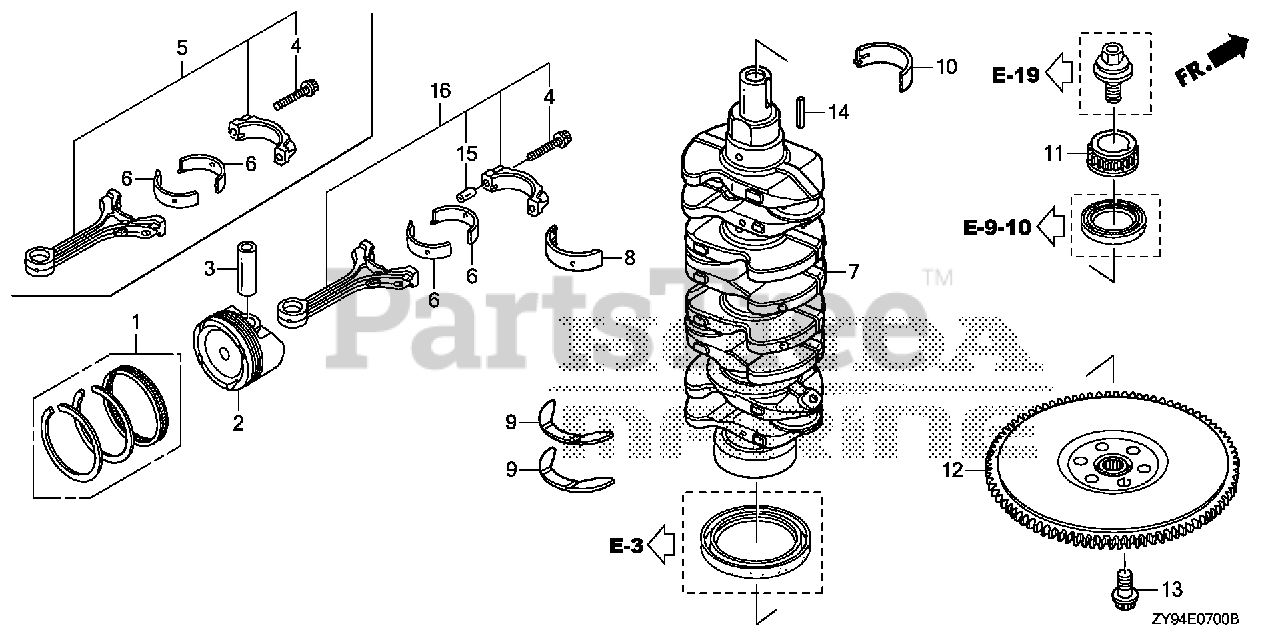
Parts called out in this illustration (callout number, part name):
1	RING SET, PISTON (STD)
1	RING SET, PISTON (0.25)
2	PISTON (STD)
2	PISTON (0.25)
3	PIN, PISTON
4	BOLT, CONNECTING ROD
5	ROD, CONNECTING
6	BEARING A, CONNECTING ROD (BLUE) (DAIDO)
6	BEARING B, CONNECTING ROD (BLACK) (DAIDO)
6	BEARING C, CONNECTING ROD (BROWN) (DAIDO)
6	BEARING D, CONNECTING ROD (GREEN) (DAIDO)
6	BEARING E, CONNECTING ROD (YELLOW) (DAIDO)
6	BEARING F, CONNECTING ROD (PINK) (DAIDO)
6	BEARING G, CONNECTING ROD (RED) (DAIDO)
7	CRANKSHAFT
8	BEARING B, MAIN (UPPER) (BLACK) (DAIDO)
8	BEARING C, MAIN (UPPER) (BROWN) (DAIDO)
8	BEARING D, MAIN (UPPER) (GREEN) (DAIDO)
8	BEARING E, MAIN (UPPER) (YELLOW) (DAIDO)
8	BEARING F, MAIN (UPPER) (PINK) (DAIDO)
8	BEARING G, MAIN (UPPER) (RED) (DAIDO)
8	BEARING H, MAIN (UPPER) (WHITE) (DAIDO)
9	WASHER, THRUST
10	BEARING B, MAIN (LOWER) (BLACK) (DAIDO)
10	BEARING C, MAIN (LOWER) (BROWN) (DAIDO)
10	BEARING D, MAIN (LOWER) (GREEN) (DAIDO)
10	BEARING E, MAIN (LOWER) (YELLOW) (DAIDO)
10	BEARING F, MAIN (LOWER) (PINK) (DAIDO)
10	BEARING G, MAIN (LOWER) (RED) (DAIDO)
10	BEARING H, MAIN (LOWER) (WHITE) (DAIDO)
11	SPROCKET, CAM CHAIN (23T)
12	FLYWHEEL *BLACK* (BLACK)
13	BOLT (12MM)
14	KEY, SPECIAL
15	PIN A, DOWEL (8X10)
16	ROD, CONNECTING
